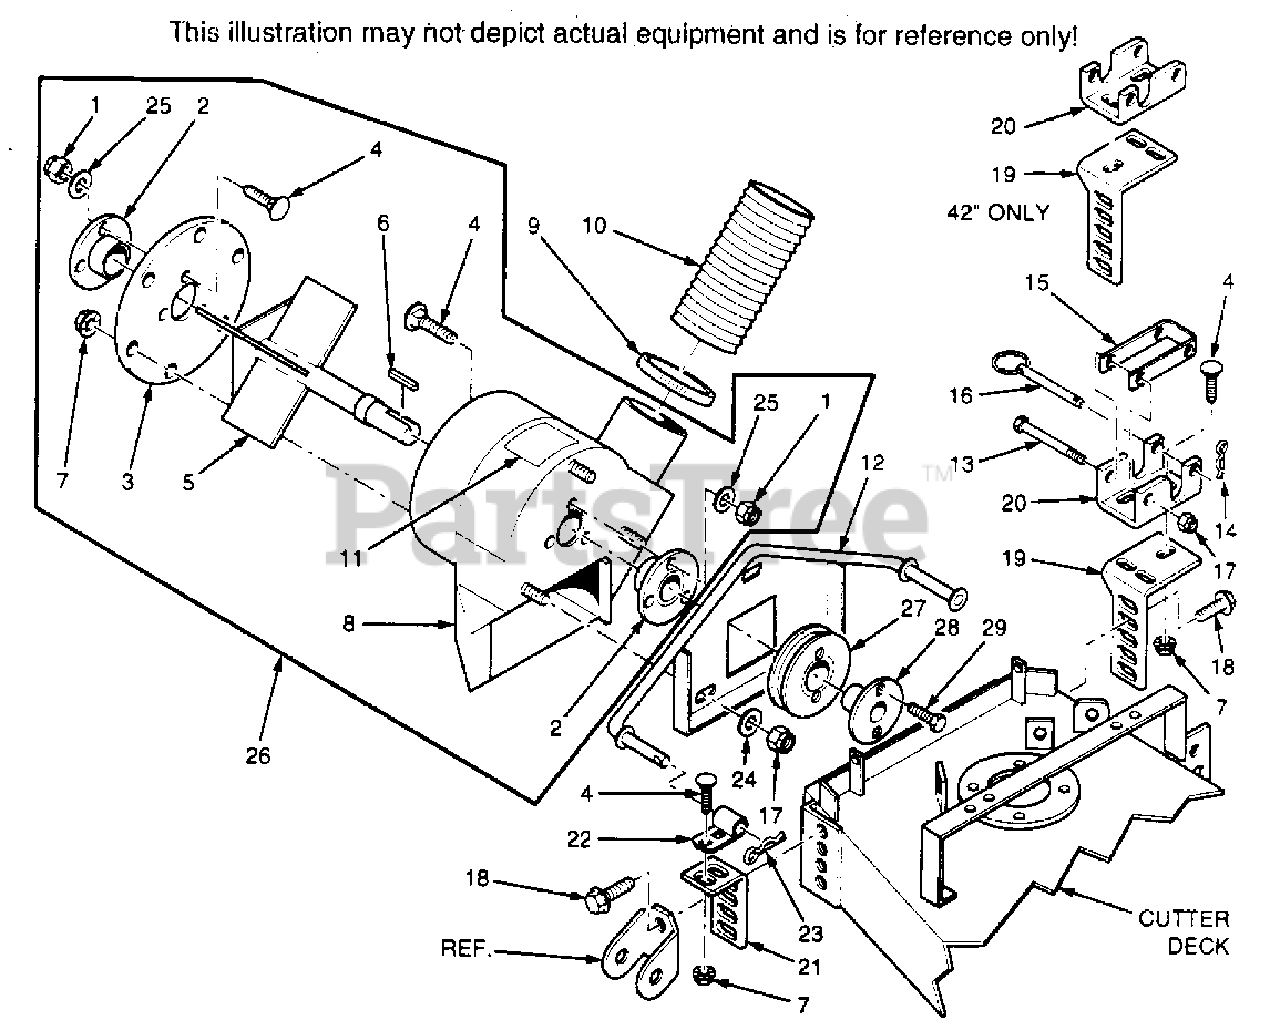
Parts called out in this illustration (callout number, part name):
1	NUT, ELASTIC STOP 5/16-18
2	BEARING ASSEMBLY
3	COVER, BLOWER HOUSING
4	CARRIAGE BOLT, 5/16-18 X .75
5	FAN WELDMENT
6	KEY, .25 X .25 X 1.50
7	NUT, SERR. FLANGE 5/16-18
8	BLOWER HOUSING WELDMENT W/DECALS
9	CLAMP, HOSE
10	HOSE, 6" X 48"
11	DECAL, DANGER
12	BLOWER MOUNTING WELDMENT
13	BOLT, HEX HEAD 3/8-16 X 4"
14	HAIR PIN, .094 DIA. X 1.62
15	LATCH
16	RING PIN
17	NUT, ELASTIC STOP 3/8-16
18	CAPSCREW, SERR. FLANGE 3/8-16 X 1
20	LATCH PLATE
21	MOUNTING BRACKET, FRONT
22	MOUNTING WELDMENT, FRONT
23	HAIR PIN, .148 DIA. X 2.75
24	FLAT WASHER, 3/8(.391 X .938 X .105)
25	FLAT WASHER, 5/16(.344 X .688 X .065)
26	BLOWER HOUSING ASSEMBLY
28	TAPERED HUB, 1.00 BORE
29	BOLT, HEX HEAD .25-20 X .75
